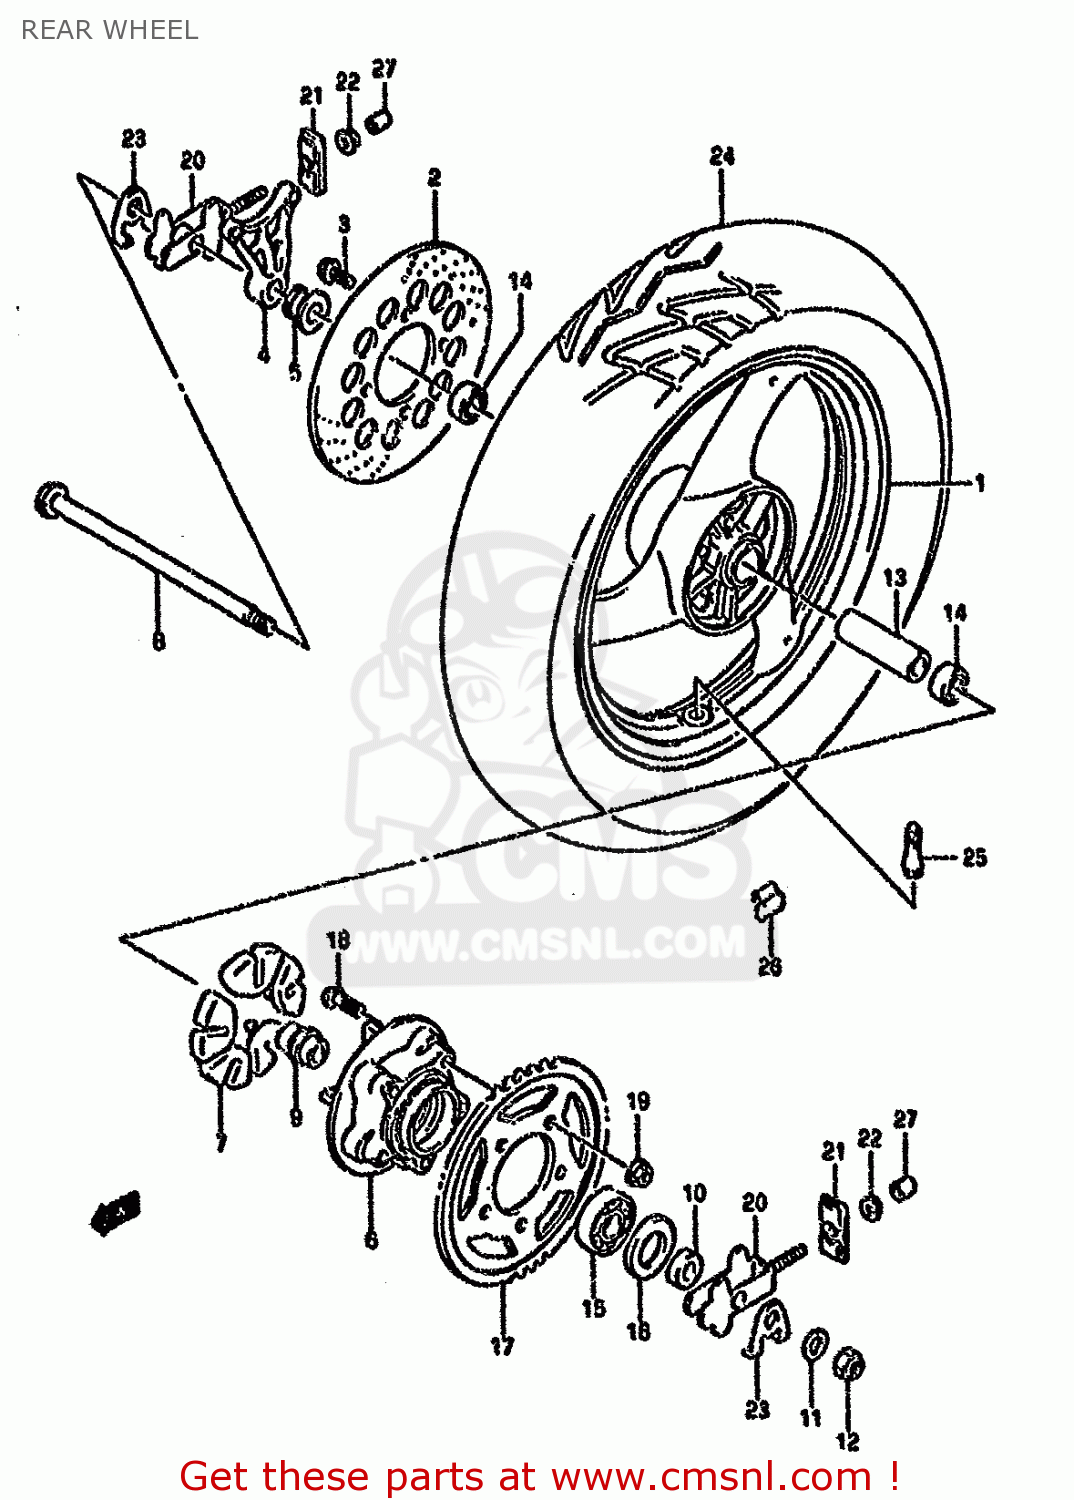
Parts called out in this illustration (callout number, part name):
1	WHEEL,RR(MT3.50X17)
2	DISC,RR BRAKE
3	BOLT
4	BRACKET,RR,CALIPER
5	SPACER,RR AXLE,R
6	DRUM,RR SPROCKET
7	ABSORBER,RR HUB SHOCK
8	AXLE,REAR
9	RETAINER,RR SPROCKET DRUM
10	SPACER,RR AXLE,L
11	WASHER(17X30X3)
12	NUT 16MM
13	SPACER(17.5X25X88)
14	BEARING
15	BEARING(25X62X17)
16	SEAL,OIL(35X62X8)
17	SPROCKET,RR(NT:39-520)
18	BOLT
19	NUT
20	ADJUSTER,CHAIN
21	PLATE,CHAIN ADJUSTER GUIDE
22	NUT
23	WASHER,CHAIN ADJUSTER
24	TIRE,T/L(130/70-17 62H)
25	VALVE,TIRE
26	BALANCER,WHEEL
27	CAP,CHAIN ADJUSTER
